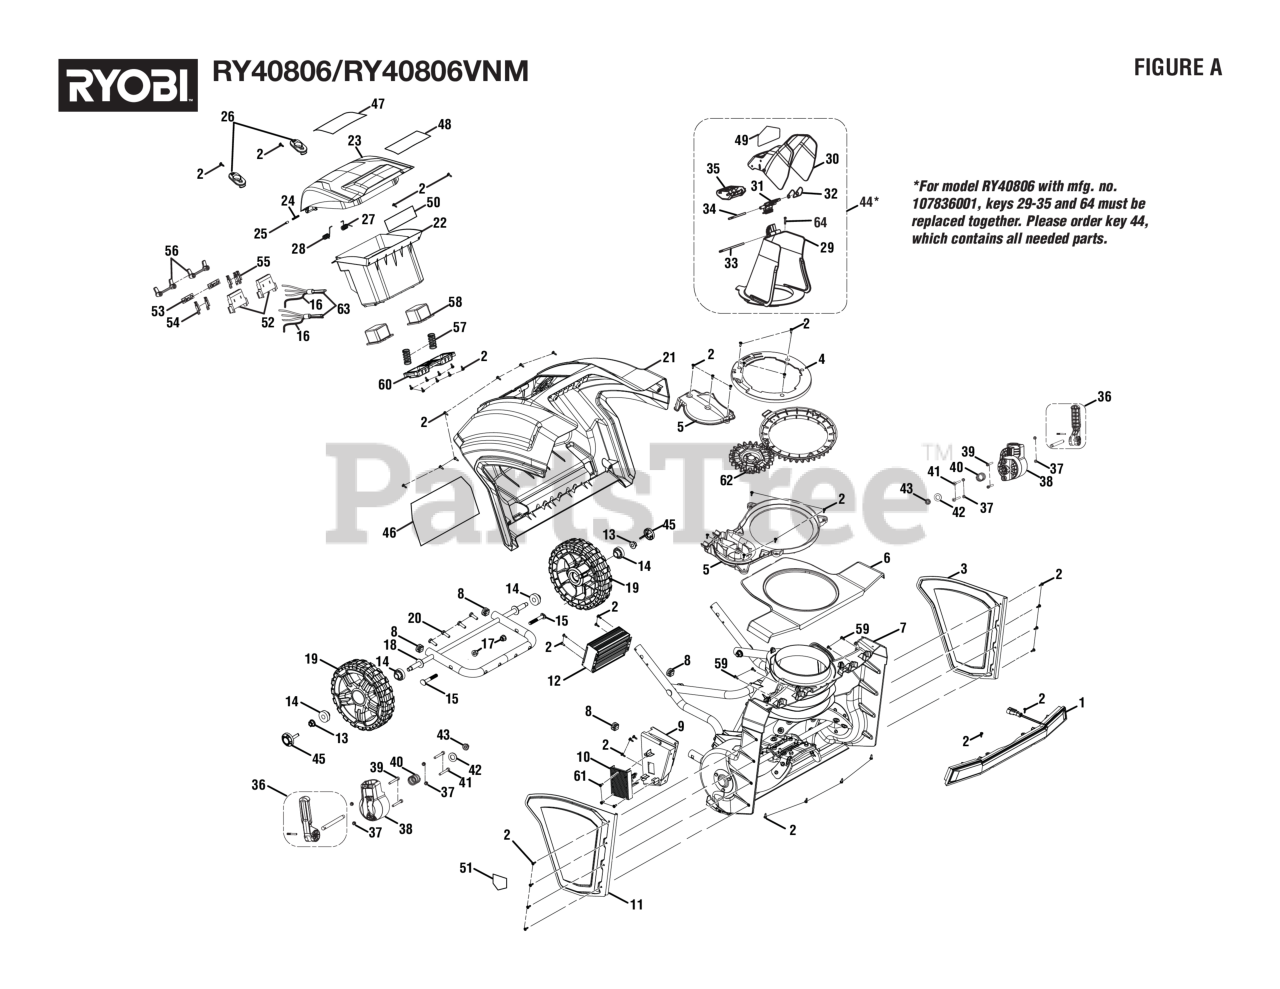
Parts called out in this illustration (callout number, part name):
1	LED Light Assembly
2	Screw (M4.2 x 12 mm, T20 Torx Pan Hd.)
3	Left Side Cover
4	Chute Rotation Bezel
5	Chute Rotation Assembly
6	Top Housing Cover
7	Auger Housing Assembly
9	Mount Assembly
10	Battery Controller
11	Right Side Cover Assembly
12	Brushless Motor Controller
13	Lock Nut (3/8-16, Flange)
14	Wheel Spacer
15	Bolt (M8 x 60 mm, Pan Hd.)
16	Ground Cable
17	Flange Lock Nut (M8 x 1.25 mm)
18	Axle and Lower Frame Assembly
19	8 in. Wheel Assembly
20	Screw (1/4-15 x 3/4 in., T30 Torx Pan Hd.)
21	Rear Cover Assembly
22	Battery Box Assembly
23	Battery Cover Assembly
24	Compression Spring
25	Battery Door Axle
27	Torsion Spring (RH)
28	Torsion Spring (LH)
29	Upper Chute
30	Chute Deflector
31	Latch
32	Chute Deflector Spring
33	Pin (Deflector)
34	Pin (Latch)
36	Cam Latch Assembly
38	Knuckle Assembly
39	Cap Screw (M5 x 45 mm, T25 Torx Soc. Hd.)
40	Compression Spring
41	Screw (M5 x 35 mm, T25 Torx Pan Hd.)
42	Washer (OD24 x ID12.5 x 2.5t)
43	Flange Nut (M8, Flywheel)
44	Chute Deflector Assembly w/Label
45	Wheel Hub
46	Data/Warning Icons Label
47	Battery Notice Label
48	Logo Label (Battery Cover)
49	Chute Warning Icons Label
50	Recommended Battery Usage Label
51	Danger Label (No Hands/Feet)
52	Battery Connector
53	PLASTIC, BATTERY COVER CONNECTOR,
54	STAMPING I BATTERY CONTACT PLATE TERMINA
55	Contact Plate Terminal
56	Hold-Down Tab
57	Compression Spring
58	Battery Ejector Post
59	Screw (M3 x 8 mm, Pan Hd., Pan Hd)
60	Spring Retainer
61	Screw (M4 x 18 mm, T20 Torx Pan Hd.)
62	Chute Gear Assembly
63	Wire Assembly
64	Screw (M4 x 20 mm, Philllips -Pan Hd., RY40806VNM)
